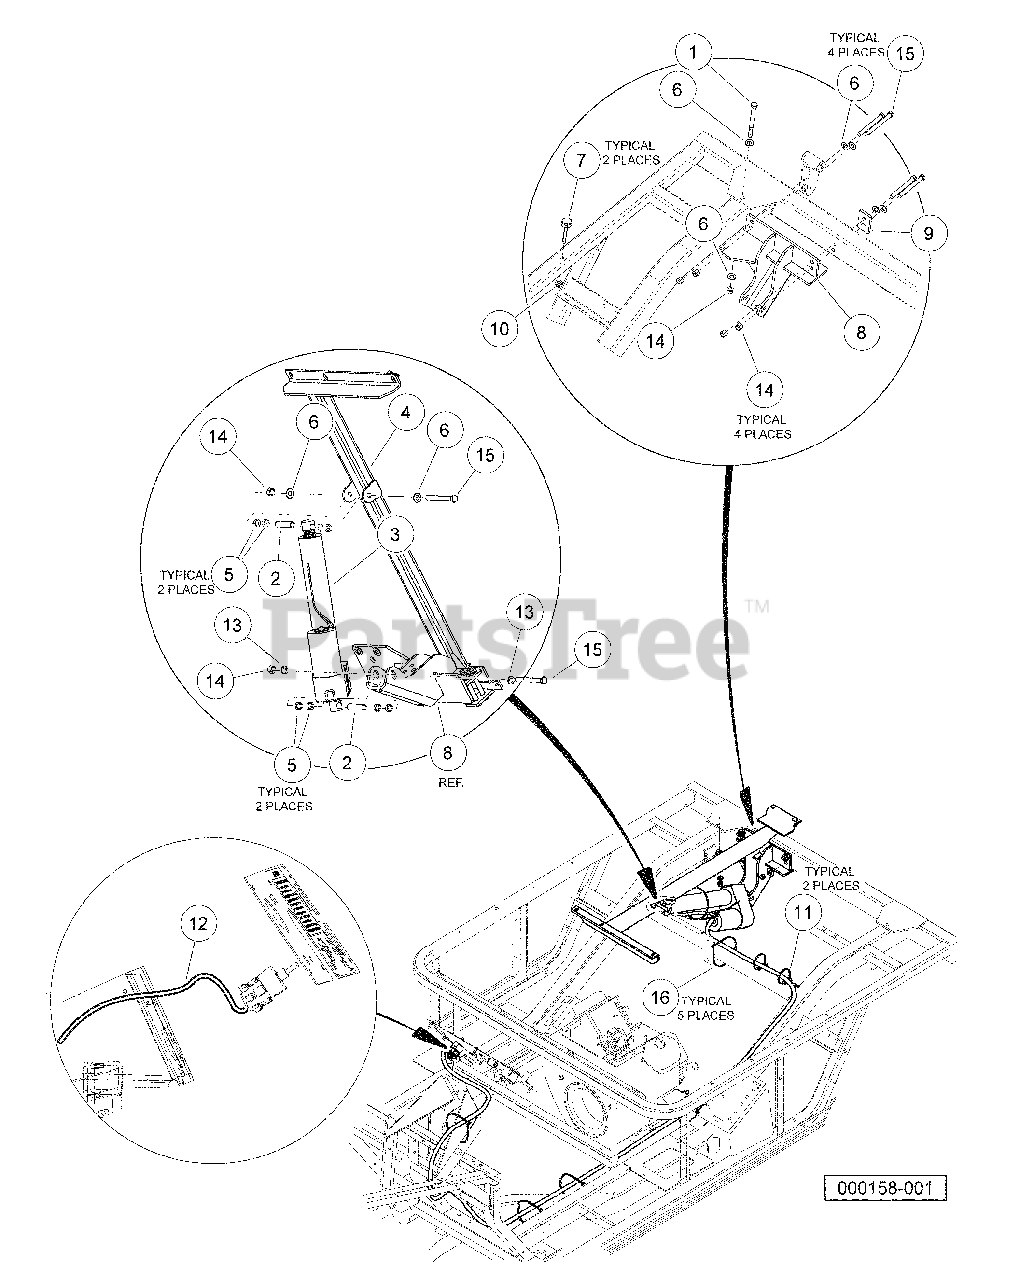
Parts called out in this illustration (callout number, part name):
1	Bolt, 3/8-16 X 4.25 Hex Head
2	Bushing Long
3	Actuator Assembly, Electric.
4	Asm, Actuator Adapter
5	Body Spacer
6	Washer, 3/8 Type B Hard Flat
7	Bumper, Bed, Mtg, Front
8	Weldment, Bracket, Actuator
9	Plate, Back
10	Lock Nut, Flg M8 X 1.25 Nylon
11	Tie Wrap, 8.00" With Mount
12	Wire Harness, Electric Lift
13	Washer, Lock, Hel Sp 3/8 Reg
14	Locknut, 3/8-16 Hex
15	Screw, 3/8-16 X 3.375 Hex Cap
16	Tie Wrap, 8" Nylon
